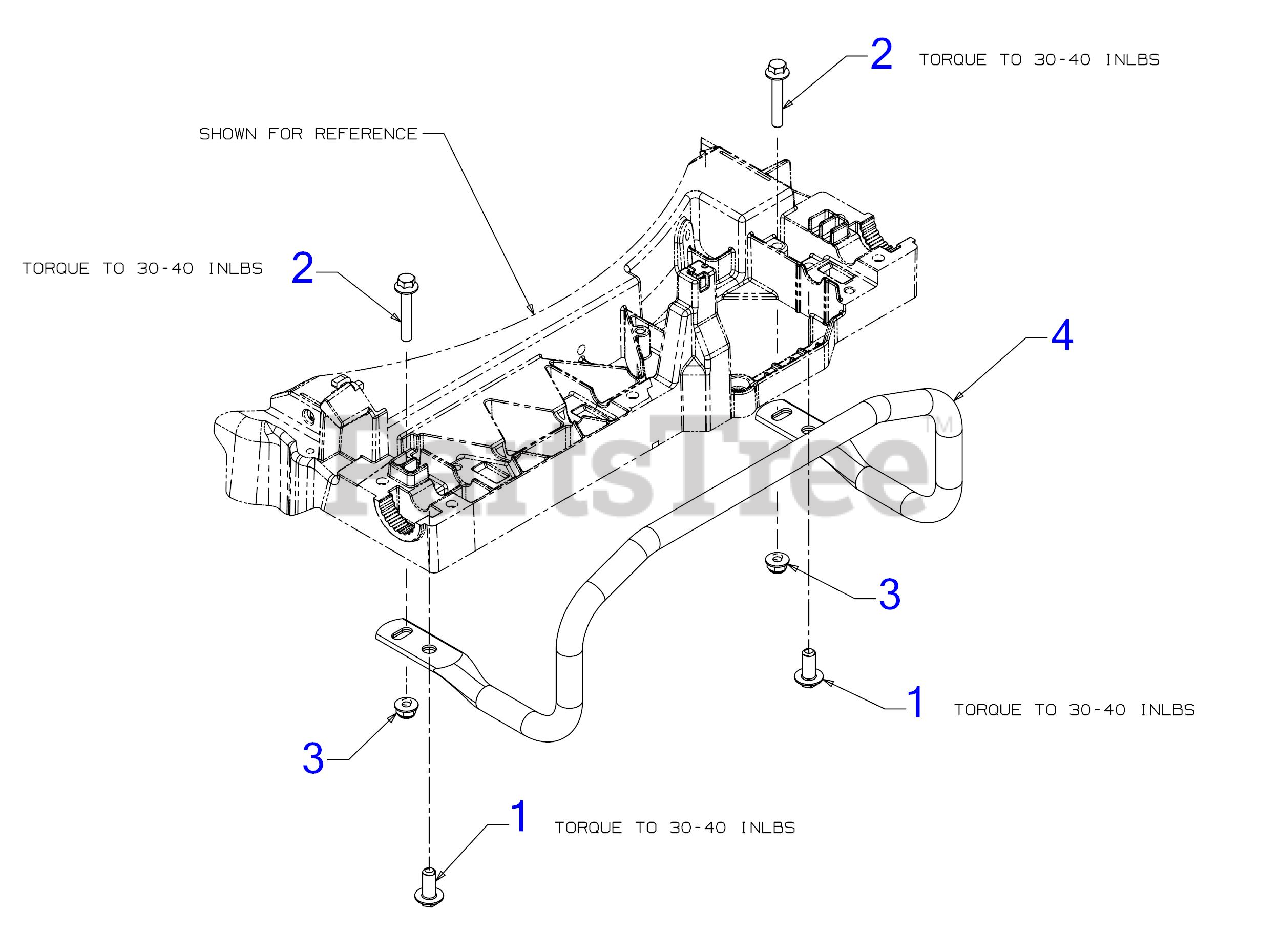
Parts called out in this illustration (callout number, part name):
1	SCREW 5/16-14 x .750
2	SCREW 1/4-20 x 1.50 GR5
3	FLANGE LOCK NUT
